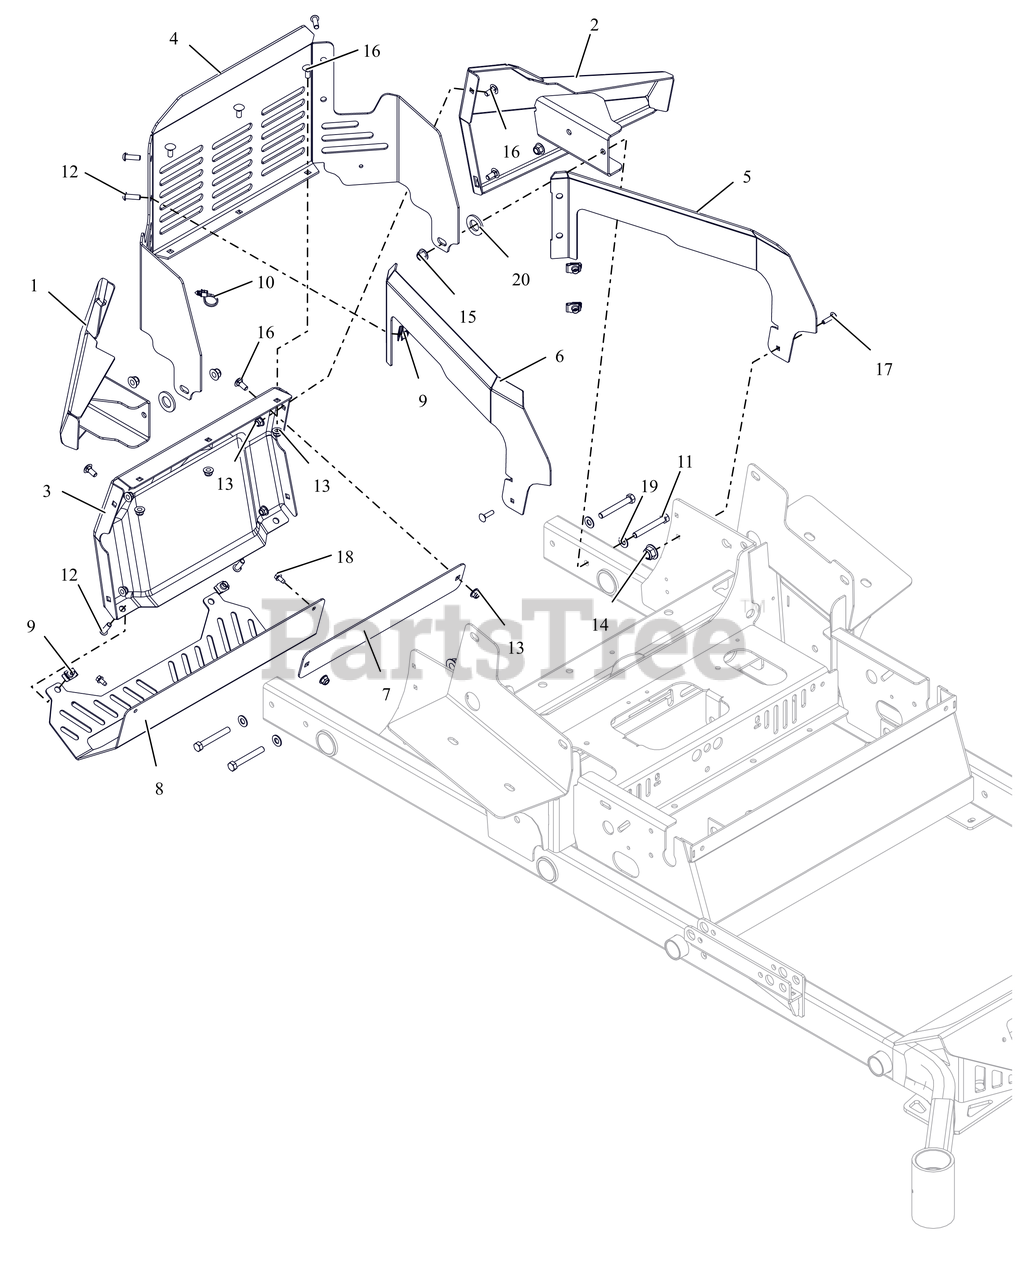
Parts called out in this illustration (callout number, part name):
1	WMT,RH REAR BMPR WING W/DECAL
2	WMT,LH REAR BMPR WING W/DECAL
3	PT200/400 REAR BUMPER - BLACK
4	PT400 ENGINE GUARD - BLACK
5	HOOD STYLE TRIM (LEFT) - RED
6	HOOD STYLE TRIM (RIGHT) - RED
7	BACKER PLATE - RED
8	PT200/400 MUFFLER GUARD - BLK
9	NUT-CLIP RETAINER 5/16-18X.56
10	CABLE TIE W/ TREE (.25 HOLE)
11	BLT, HEX .38-16X2.75 G5 ZCC
12	BLT,SHCS-BTN .31-18X1.00 ZCC
13	NUT,NYL-FLG .31-18 GF ZCC
14	NUT,NYL-FLG .50-13 GF ZCC
15	NUT,NYL-FLG .38-16 GF ZCC
16	BLT,RHSN .31-18X.75 G5 ZCC
17	BLT, RHSN .25-20X1.00 G5 ZCC
18	SCR-TAP .25-20X.50 HWH ZCC
19	WSHR,FLT .406X.812X.065 ZCC
20	WSHR-FL-STL 0.812X1.469X0.134 ZCC
